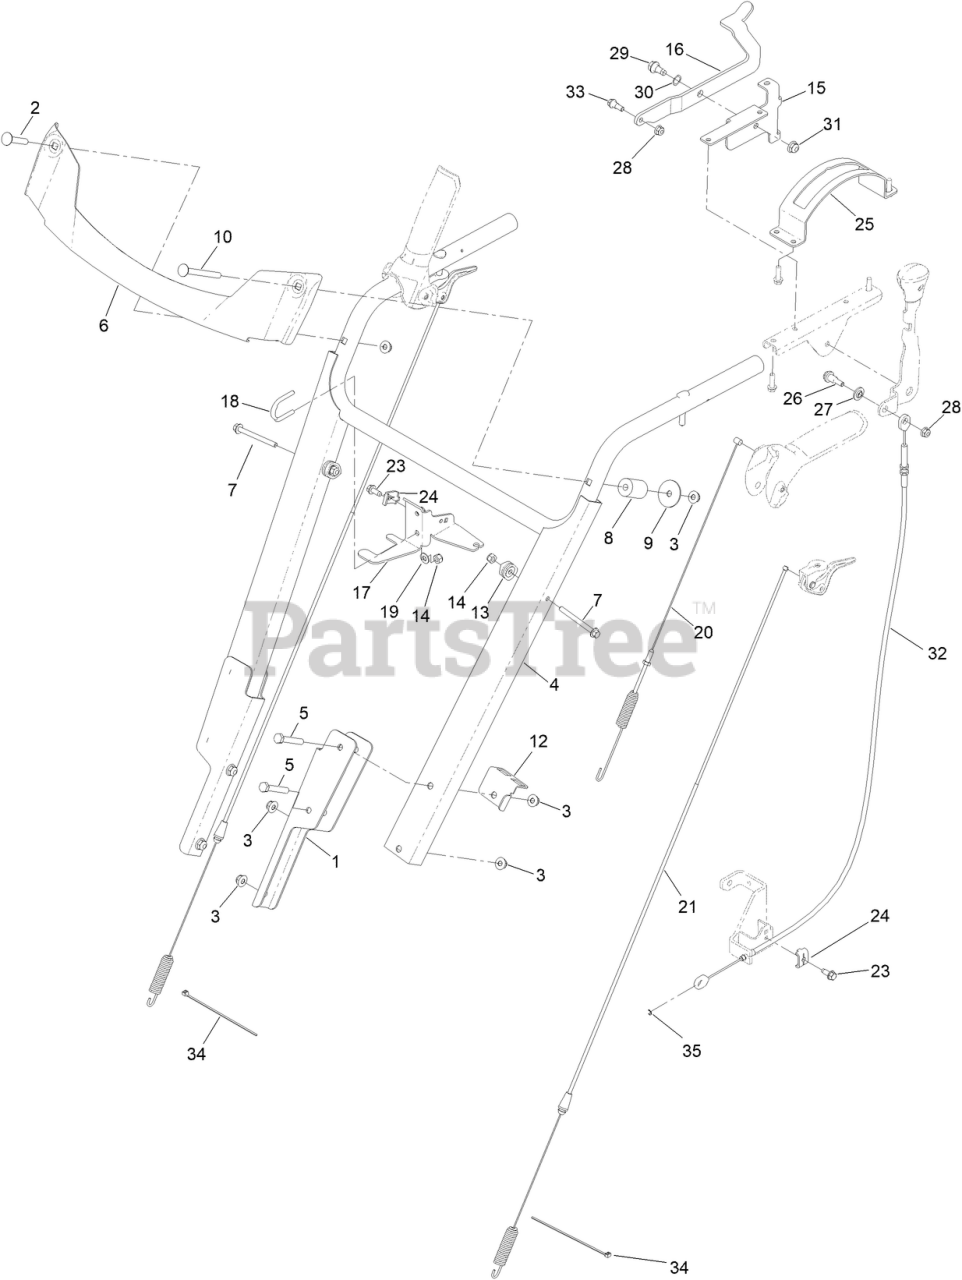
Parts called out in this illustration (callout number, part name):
1	BRACKET-HANDLE, LOWER
2	SCREW-CARR
3	NUT-HF
4	HD HANDLE ASM
5	SCREW-HH
6	TRIM-METAL, HD
7	SCREW-HHF
8	SPACER
9	WASHER-FLAT
10	SCREW-CARR
12	BRACKET-STICK, CLEANOUT
13	CLAMP-CABLE
14	NUT-HEX
15	BRACKET-LEVER
16	LEVER-ADJUSTMENT, TRACK
17	BRACKET-CABLE, SPEED
18	CLAMP-LIGHT
19	WASHER-FLAT
20	CABLE-TRACTION
21	CABLE-CLUTCH
23	SCREW-HWH
24	CLAMP-CABLE
25	GATE-SHIFT, SPEED
26	BOLT-SHOULDER
27	WASHER-STEPPED
28	NUT-FLANGE, NI
29	SCREW-SHOULDER
30	WASHER, WAVE
31	NUT-HF
32	CABLE-HYDRO, PUSH PULL
33	BOLT-SHOULDER
34	TIE-CABLE
35	RING-RETAINING, EXT
